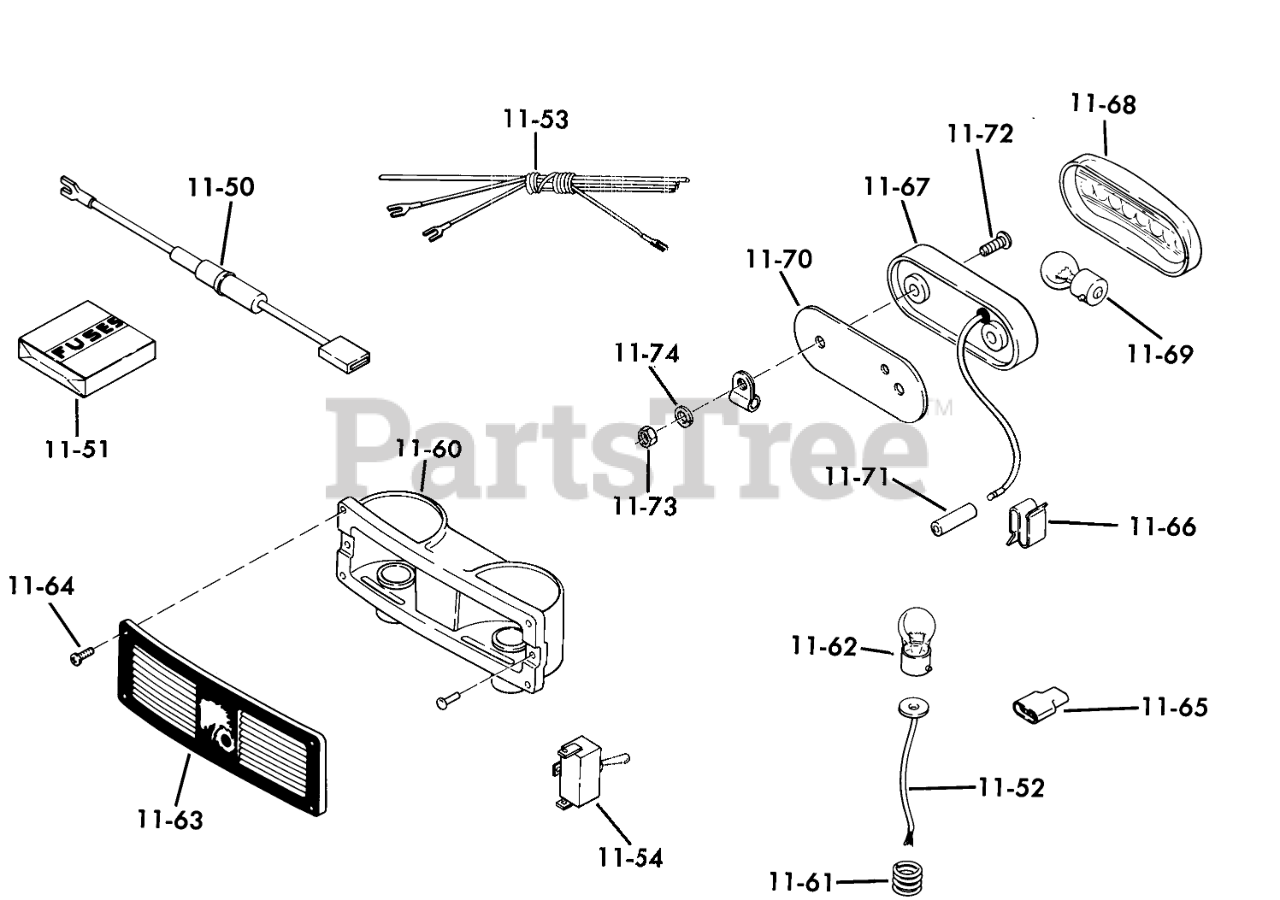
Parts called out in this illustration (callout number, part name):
11-50	ASSY FUSED CONNECTOR
11-52	WIRE ASSY
11-53	Wire Harness-Lights
11-54	SWITCH-LIGHTS
11-60	ASSY REFLECTOR HOUSI
11-61	SPRING
11-62	BULB
11-63	Lens
11-64	Pan HD Swage
11-65	CONNECTOR 3 WIRE
11-66	SPEED CLIP
11-67	Base
11-68	Lens
11-69	Bulb
11-70	Mounting Pad
11-71	CONNECTOR 2 WIRE
11-72	Screw
11-73	Nut
11-74	Lockwasher
